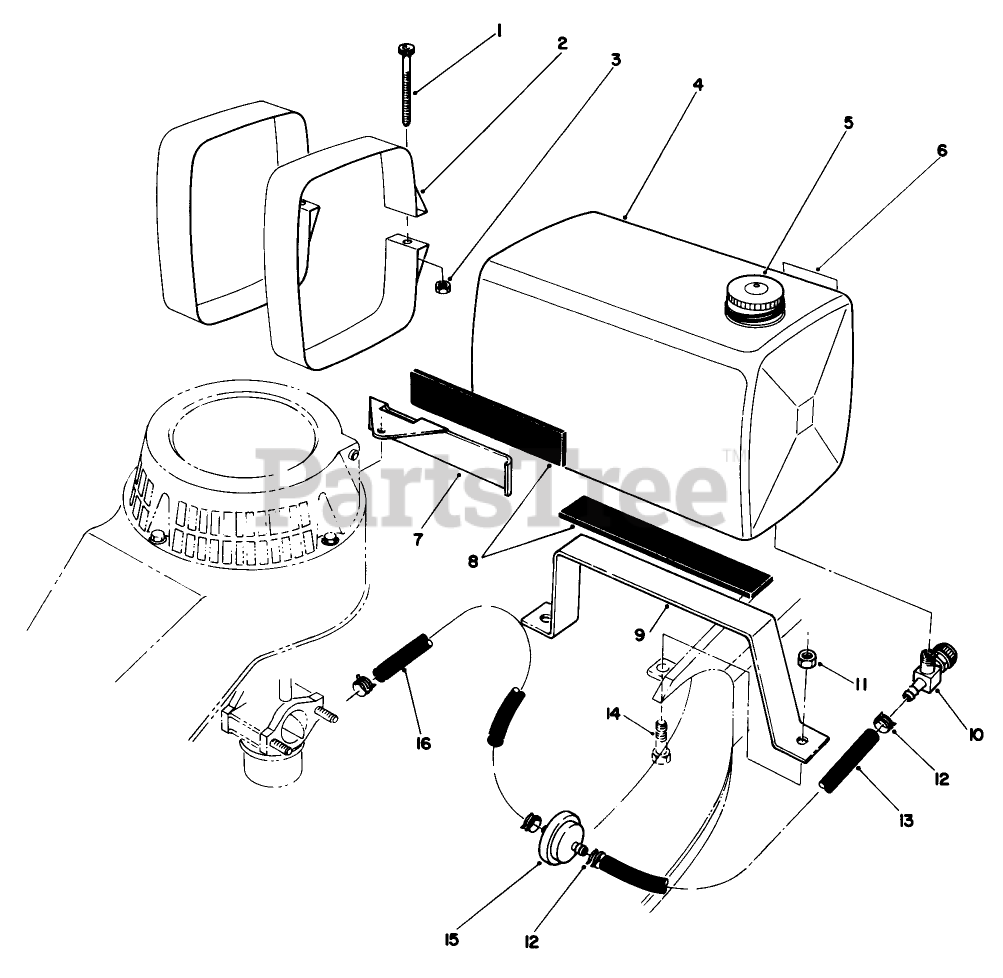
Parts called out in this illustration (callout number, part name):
1	SCREW-HSH
2	TANK MTG STRAP WA
3	NUT-HEX
6	DECAL - FUEL
7	FRT TANK MOUNT *
8	ISOLATOR PAD
11	NUT-LOCK, NI
12	CLAMP-FUEL LINE
13	HOSE-FUEL
14	SCREW-HH
15	FILTER-FUEL
16	HOSE-FUEL
